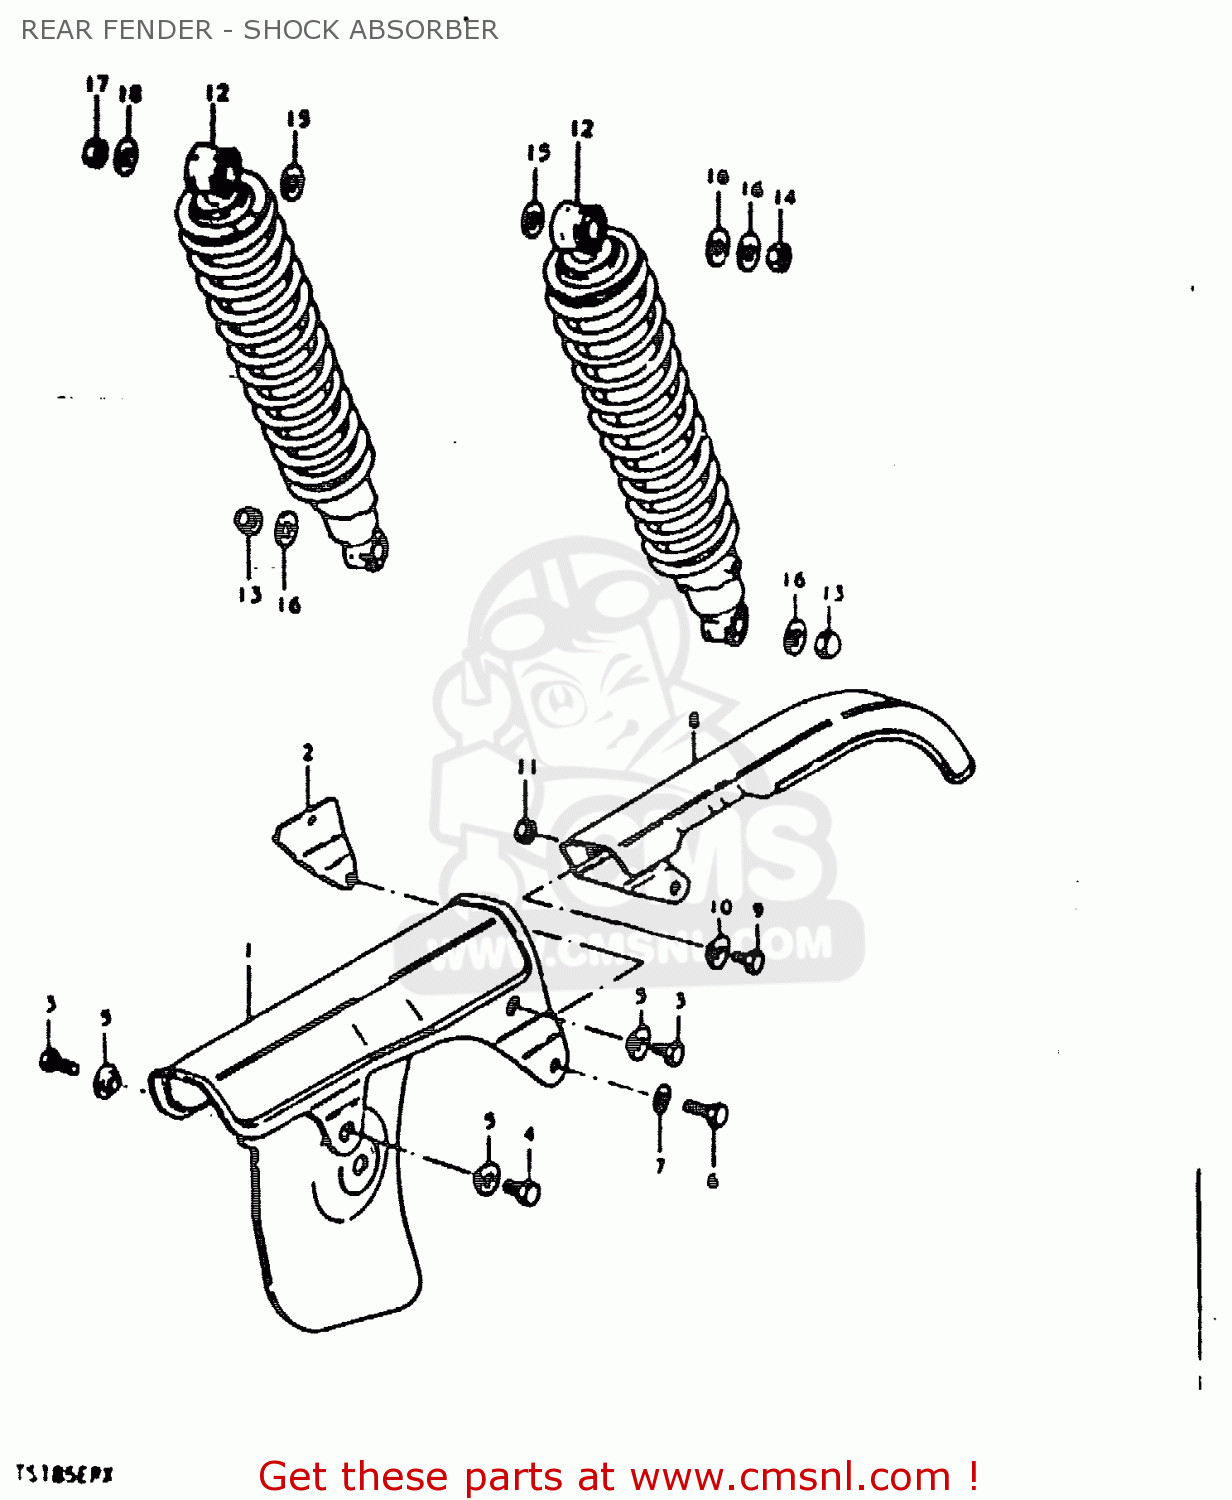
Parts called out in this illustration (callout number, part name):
1	CASE,CHAIN
2	REINFORCEMENT,CHAIN
3	BOLT(6X8)
4	BOLT
5	WASHER
6	BOLT
7	WASHER
12	ABSORBER ASSY,RR SHOCK
13	NUT, LOWER LH
14	NUT
15	WASHER
16	WASHER
17	NUT
18	WASHER (12.5X24X3.2)
